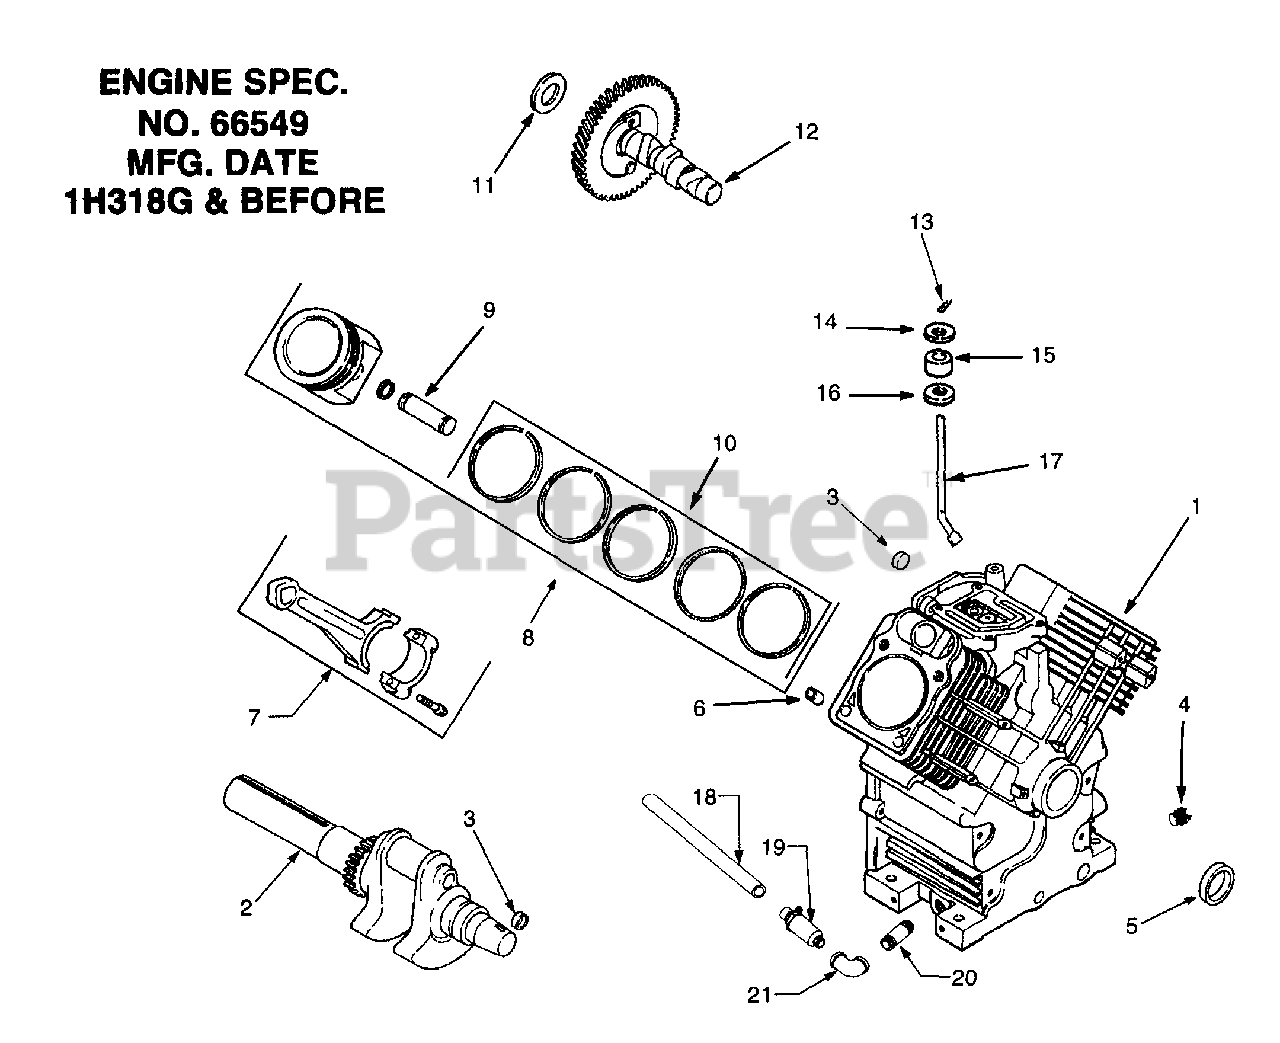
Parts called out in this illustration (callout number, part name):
1	Cylinder Block (Use Miniblock)
2	Crankshaft
4	Plug, Hex Head, 3/8 NPTF
5	Seal, Oil
6	Pin, Dowel Locating
7	Rod, Connecting, Std
8	Piston w/Ring Set, Std
9	Retainer, Piston Pin
10	Ring Set, Std
11	Shim, Camshaft, .0320
12	Camshaft
14	Washer, Plain
15	Seal, Governor Cross Shaft
16	Washer, Plain
17	Shaft, Governor Cross
18	Hose, Oil Drain 12 in.
19	Drain, Oil
20	Pipe, Straight
21	Elbow, 90°.
